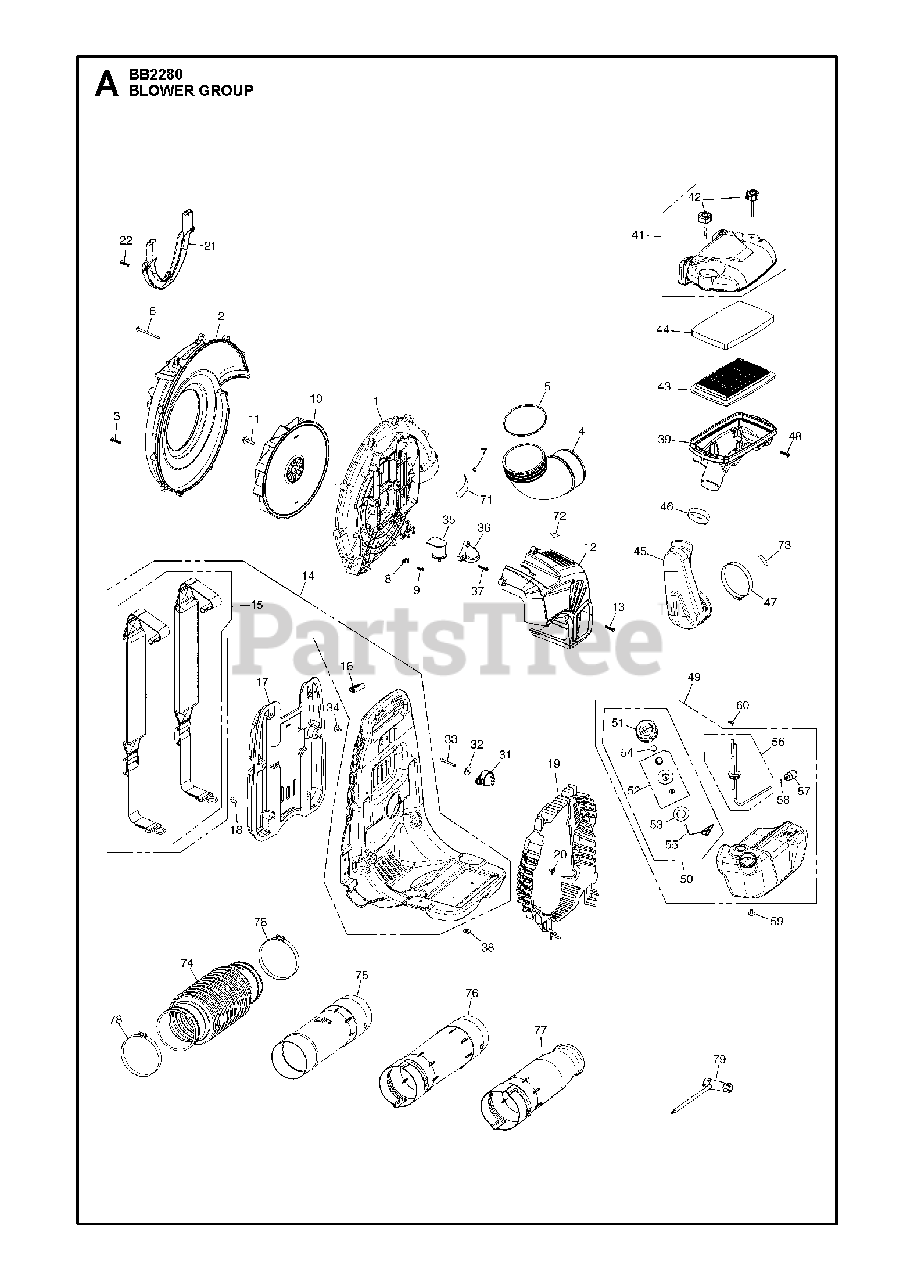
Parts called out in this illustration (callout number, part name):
1	CASE VOLUTE
2	COVER VOLUTE
8	CLAMP
10	FAN
12	COVER ENGINE JONSER
14	ASSY FRAME
15	ASSY BAND
16	CLIP
18	CLIP
20	CLIP
21	COVER
31	DAMPER UPPER
33	BOLT
41	COVER ASSY
42	KNOB BOLT
43	ELEMENT
44	ELEMENT
45	HOSE
46	CLAMP(F64)
47	CLAMP(F96)
49	Tank Assembly
51	CAP
52	HOLDER-A
53	PACKING
54	FILTER
55	STOPPER
56	PIPE ASSY
57	FILTER ASSY
58	CLIP
60	CLIP
71	DECAL CAUTION
73	RP_LABEL,CHOKE
74	HOSE
78	CLAMP(F115)
79	SOCKET
